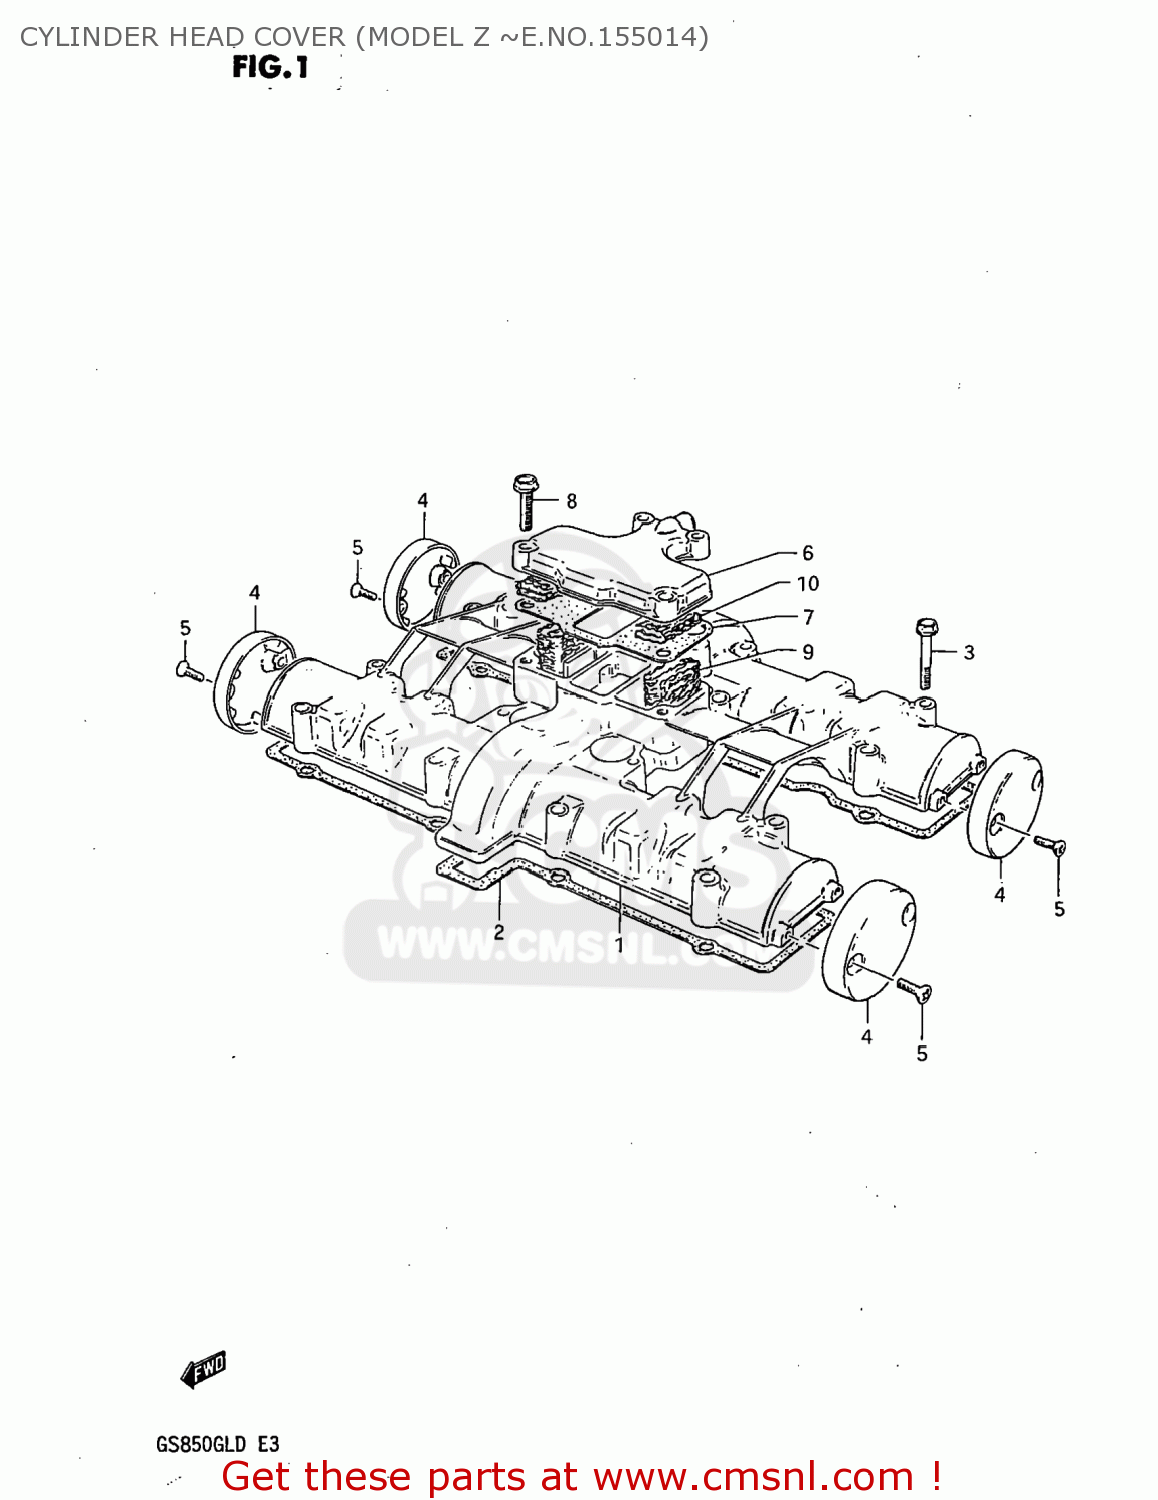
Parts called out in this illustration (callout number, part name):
1	COVER,CYLINDER HEAD
2	GASKET,CYLINDER HEAD COVER (MCA)
3	BOLT
4	CAP,CYLINDER HEAD COVER
5	SCREW(5X12)
6	COVER,BREATHER
7	GASKET (MCA)
8	BOLT
9	COVER,BREATHER
10	SEPARATOR,OIL BREATHER
